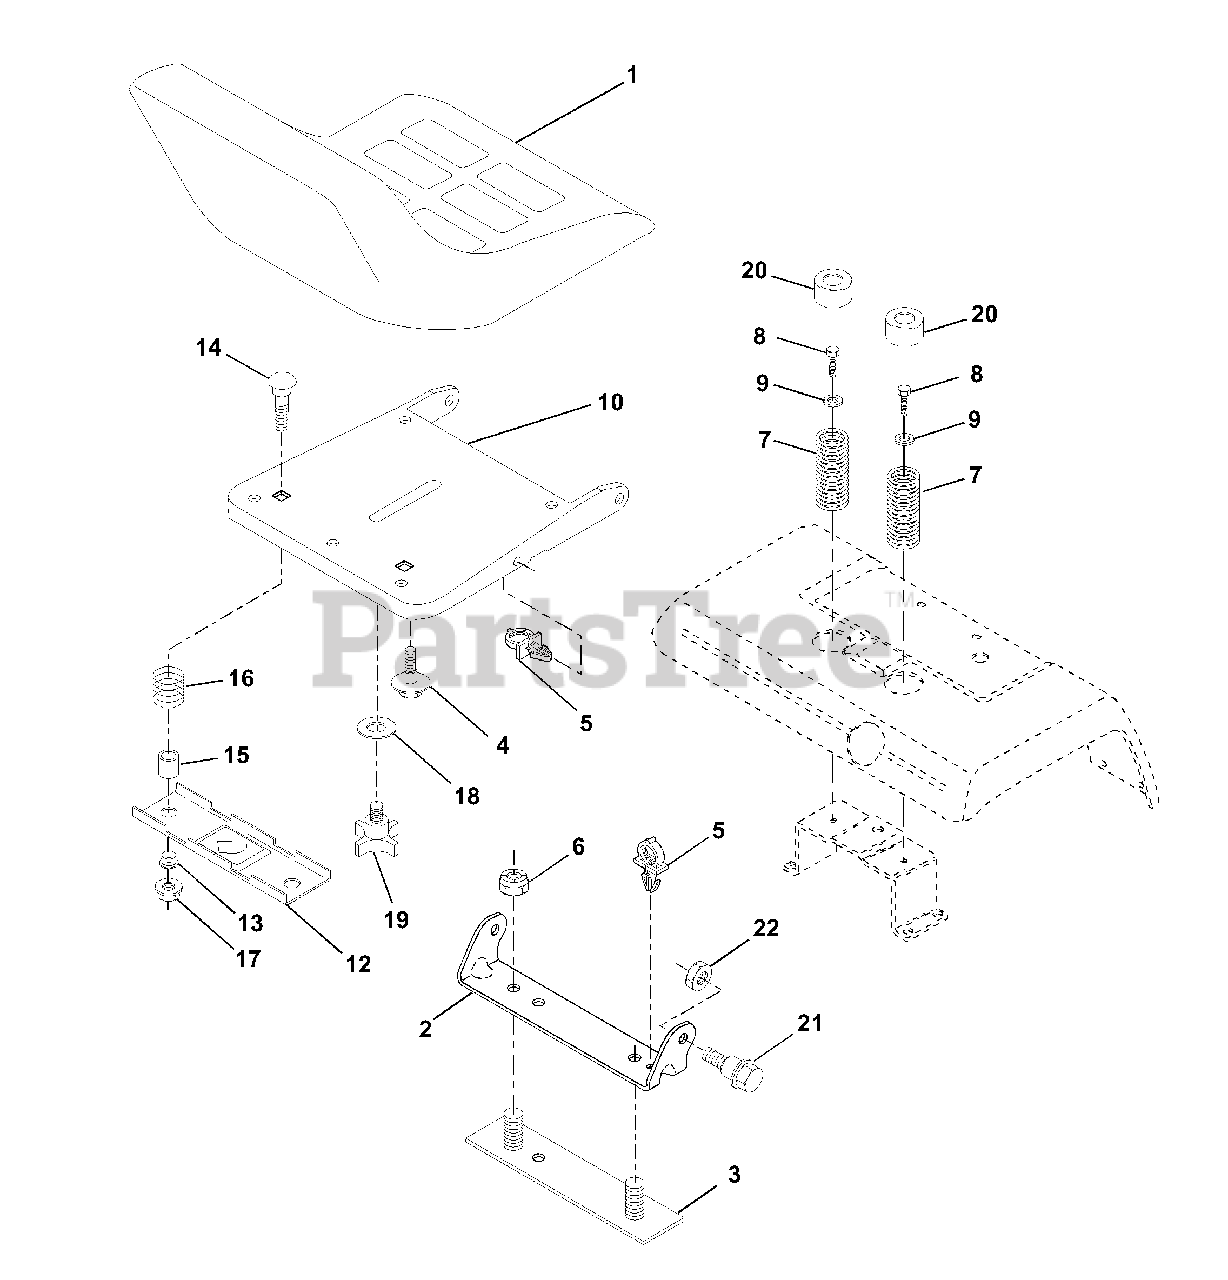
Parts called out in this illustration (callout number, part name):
1	Seat
2	Bracket, Pivot Seat
3	Strap, Fender
4	Bolt, Shoulder 5/16-18 X .62
5	Clip, Push In Hinged
6	Nut, Lock Hex W/Ins. 3/8-16 Unc
7	Spring, Seat Cprsn
8	Screw, Thdrol 5/16-18 X 1/2
9	Washer 13/32 X 1 X 14 Ga.
10	Pan, Seat
12	Bracket, Mounting Switch
13	Bushing, Snap
14	Bolt, Carriage 1/4-20 X 1-3/8
15	Spacer, Split
16	Spring, Cprsn
17	Nut, Lock 1/4 Lge Flg Gr. 5
18	Washer 17/32 X 1-3/16 X 12 Ga.
19	Knob, Seat 1/2-13 Unc
20	Cap, Spring Seat
21	Bolt, Shoulder 5/16-18 Unc
22	Nut, Crownlock 5/16-18 Unc
